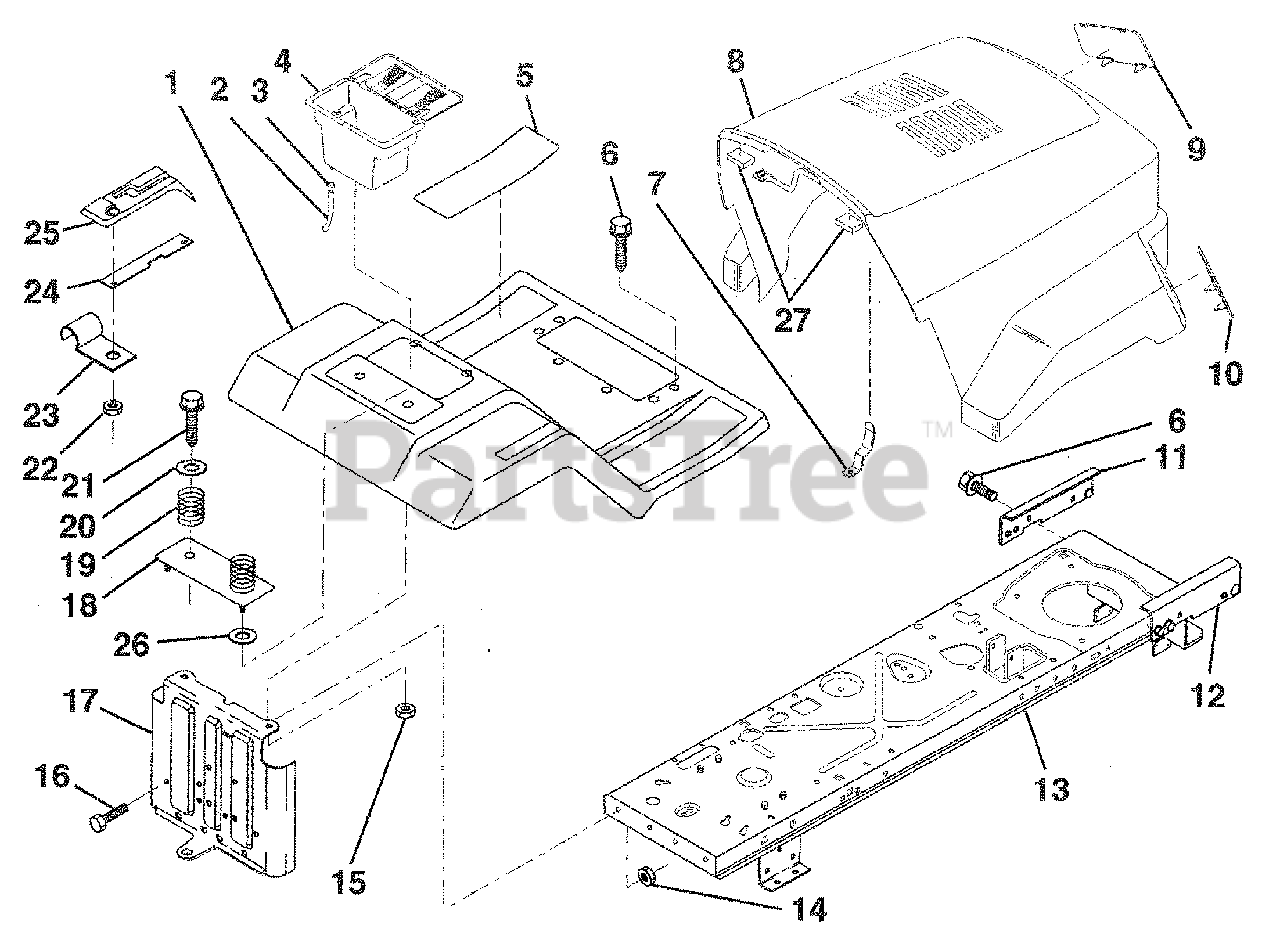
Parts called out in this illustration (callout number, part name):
1	Fender/Footrest
2	Tube, Battery Drain
3	Clamp, Hose
4	Case, Battery
5	Pad, Footrest
6	Screw, Hex Wsh. Thrdro!. 5/16-18x3/4
7	Latch, Hood
8	Hood/Grill Asm.
9	Lens, L.H.
10	Lens, R.H.
11	Bracket, Asm. Pivot Frame, L.H.
12	Bracket, Asm. Pivot Frame, R.H.
13	Assembly, Frame
14	Nut, Crownlock 5/16-18
15	Nut, Keps, Hex 1/4-20 UNC
16	Bolt, Hex Hd. 5/16-18 UNC x 3/4
18	Plate, Asm. Battery
19	Spring, Compression, Seat
20	Washer 13/32 x 1-1/4 x 12 Ga.
21	Screw Self Tapping
22	Nut, Self-Threading, Washer Head 3/16
23	Clip, Insulated
24	Bar, Shift Lock
25	Consoie, Shift Control
26	Washer 9/32 x 7/8 x 13 Ga.
27	Bumper, Hood
